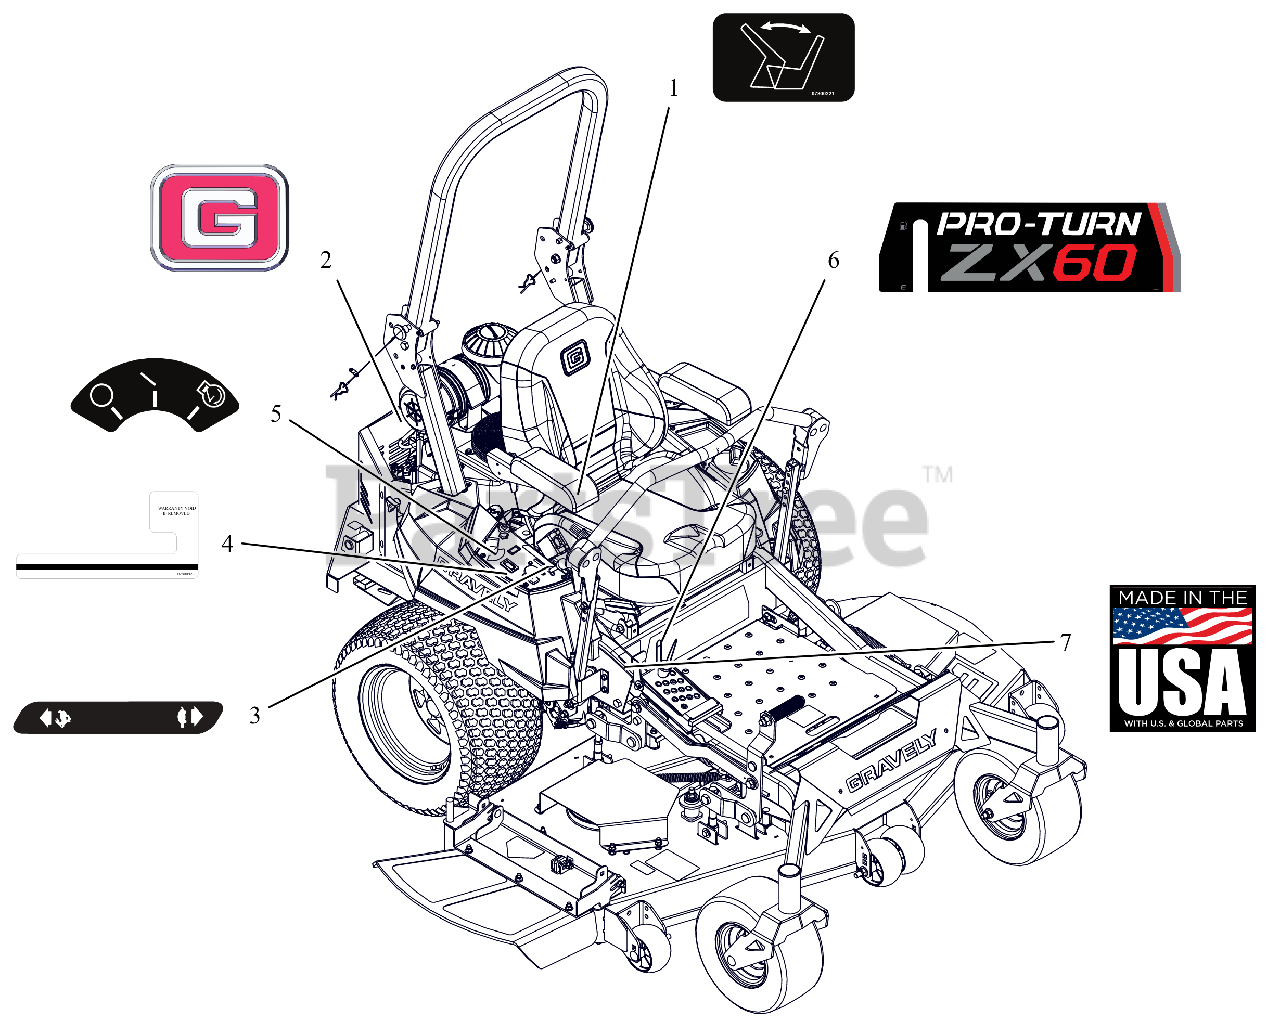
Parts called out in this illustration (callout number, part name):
1	DECAL - SEAT RELEASE
2	DECAL, GRAVELY BRAND
3	DECAL, DASH DECAL
4	DECAL,HOURMETER - SECURITY
5	DECAL, KEYSWITCH
6	DECAL, PROTURN ZX 60
7	DECAL, MADE IN USA
